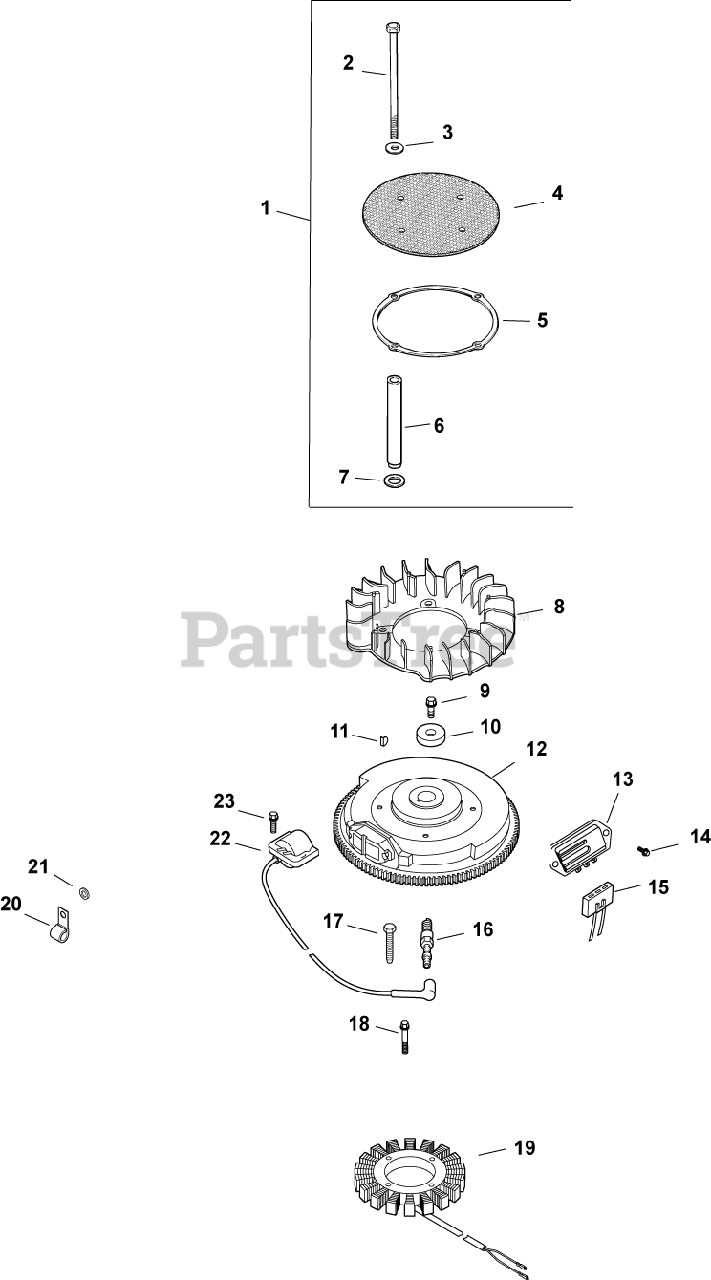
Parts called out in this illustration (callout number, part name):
1	KIT, CHOPPER SCREEN
2	SCREW, CAP M6X1.0X99.5
3	WASHER, FLAT 1/4" (O.D. 5/8")
4	SCREEN, GRASS
5	RING, SUPPORT USE 25 141 08-S
7	WASHER, SPRING 10 MM
9	SCREW, FLG M10X1.5X45 - (#25086361S)
10	WASHER, FLAT 13/32"
11	KEY, 3/16" X 5/8"
12	FLYWHEEL ASSEMBLY (LW)
13	REG/RECTIFIER (20/25 AMP)-USE 25 403 20-
14	SCREW, HEX FLANGE HI-LO
15	CONNECTOR, BODY (KM)-USE 25 155 41-S
16	PLUG, SPARK (PRO SERIES)
17	SCREW, THD FROM M5X0.8X30
18	SCREW, SKT SET #10-24X1/4"
19	KIT, 15 / 20 AMP STATOR
20	CLIP, CABLE
21	WASHER, FLAT 1/4" (O.D. 1/2")
22	MOD SPARK ADV (DSAI) -USE 24 584 64-S
23	SCREW, FLG THD FRM M5X.8X20-(#25086399S)
